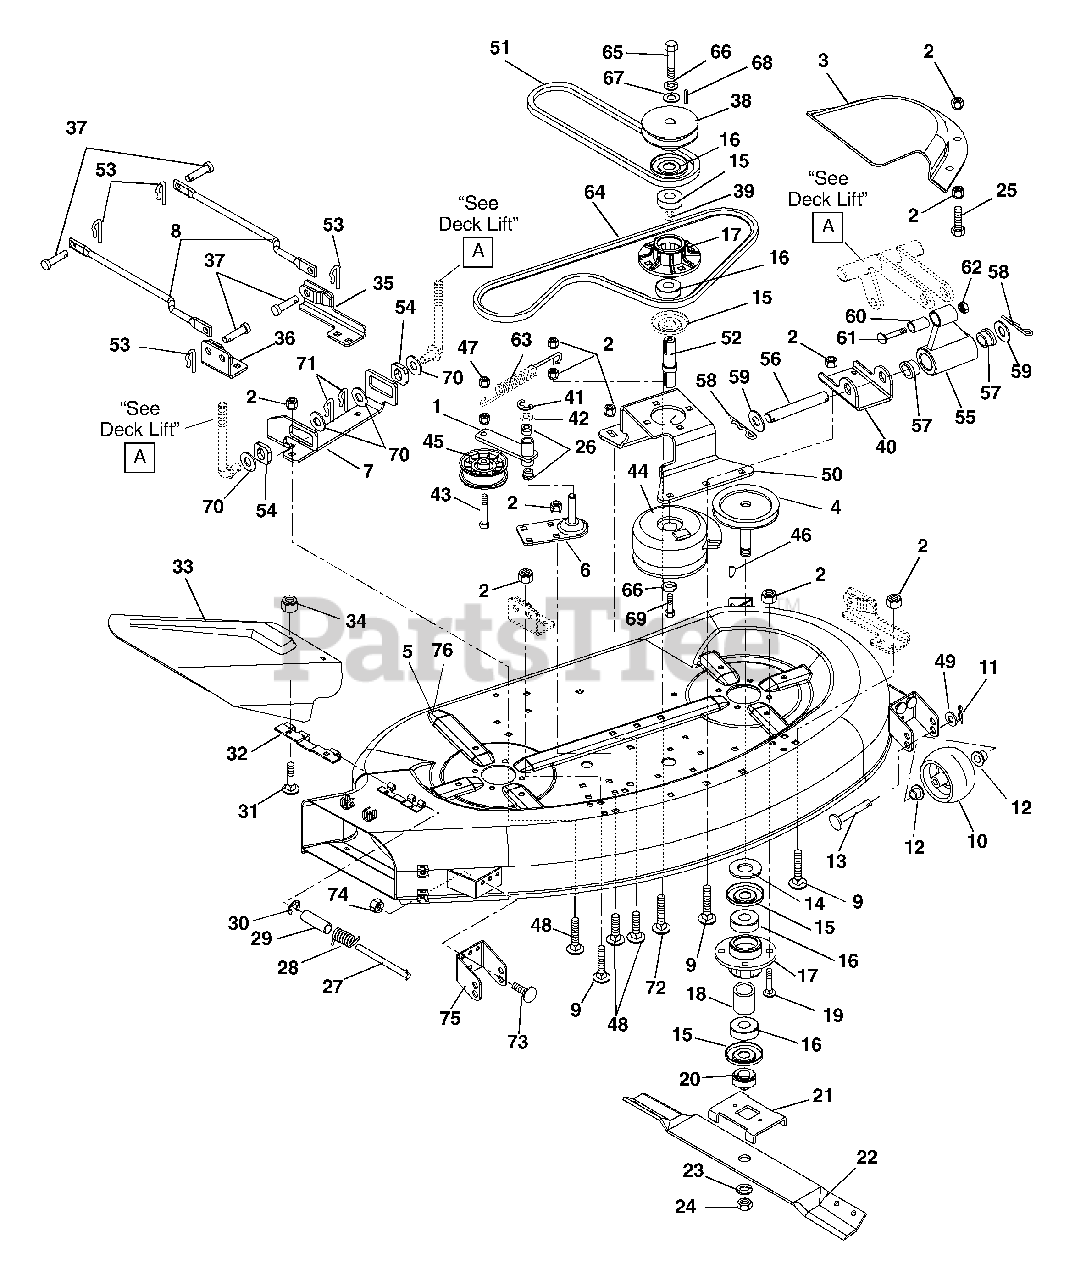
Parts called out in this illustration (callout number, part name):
1	Weldment, Idler
2	Nut, Locking Top Flange .38-16
3	Cover, 40" Deck Sheave
4	Sheave, Left Spindle
4	Sheave, Right Spindle
5	Deck, 40"
6	Bracket, Idler Mount
7	Bracket, Rear Hanger
8	Link, Stabilizer 40" Deck
9	Bolt, Round Head Square Neck .38-16 x 1.00 Grade 55
10	Roller
11	Pin, Hair Internal .08 x .18 x 1.18
12	Bushing, Flange .372 x .500 x .312 x .625
13	Clevis Pin .368/.373 x 3.25
14	Washer, Flat Steel .755 x 1.25 x .125
15	Bearing Slinger
16	Bearing, Ball .750 x 1.781 x .61
17	Spindle Housing
18	Spacer .751 x 1.00 x 1.14
19	Bolt, Round Head Square Neck .38-16 x 1.0 Grade 5
20	Retainer Hub
21	Blade Tray 48
23	Washer, Lock .75 x .188
24	Nut, Jam .75-10
25	Bolt, Hex .38-16 x 1.00 Grade 5
26	Bushing, Flange .500 x .625 x .312 x .75
28	Spring, Torsion .095 x .50 x 1.00
29	Bushing
30	Ring, Retaining External .313 x .025
31	Bolt, Round Head Square Neck .25-20 x .50
32	Hinge Plate
33	40 In Deflector
34	Nut, Locking Flange .25-20 Grade F
35	Bracket, Deck Link Left Hand
36	Bracket, Deck Link Right Hand
37	Pin, Clevis .494 x 1.00
38	Pulley, 40" Deck Input
39	Spacer .75 x 1.00 x 1.14
40	Bracket, Front Hanger
41	Ring, Retaining External .50 x .042
42	Washer, Flat Steel .505 x .880 x .072
43	Bolt, Hex .38-16 x 2.25 Grade 5
44	Electric Clutch/Brake
45	Idler, Flat 3.00 x .38
46	Key, Woodruff .188 x .625 x .31
47	Nut, Locking Center .375-16
48	Bolt, Round Head Square Neck .38-16 x .75 Grade 5
49	Bolt, Round Head Square Neck .31-18 x 1.00
50	Bracket, Spindle Housing Mount
51	Belt, 40" Deck PTO
52	Input Shaft 40" Deck
53	Clip, Spring
54	Slider, Hanger Bracket
55	Link, Front Lift
56	Pivot, Front Lift Lower
57	Bushing, 1.00 x .75 x 1.00
58	Pin, Hair
59	Washer, Flat Steel .75 x 1.47 x .134
60	Bushing, Sleeve .50 x .75 x 1.56
61	Bolt, Round Head Square Neck .50-13 x 2.75
62	Nut, Locking Center Jam .50-13
63	Spring, Tension .095 x .50 x 5.50
64	V-Belt A-Section 12.58 x .48
65	Bolt, Hex .38-16 x 01.00 Grade 8 with Epoxy Patch
66	Washer, Locking .375 x .115 Heavy
67	Washer, Flat Steel .406 x 1.375 x .135
68	Key, Square.187 x .50 x .187 Hardened
69	Bolt, Hex .38-24 x 2.00
70	Washer, Flat Steel .518 x 2.00 x .105
71	Pin, Hair External
72	Bolt, Round Head Square Neck .38-16 x 2.00 Grade 5
73	Bolt-Round Head Square Neck .31-18 x .62
74	Nut, Spin Lock Flange .312-18
75	Roller Clevis
76	Kit, 40" Deck Assembly Service
